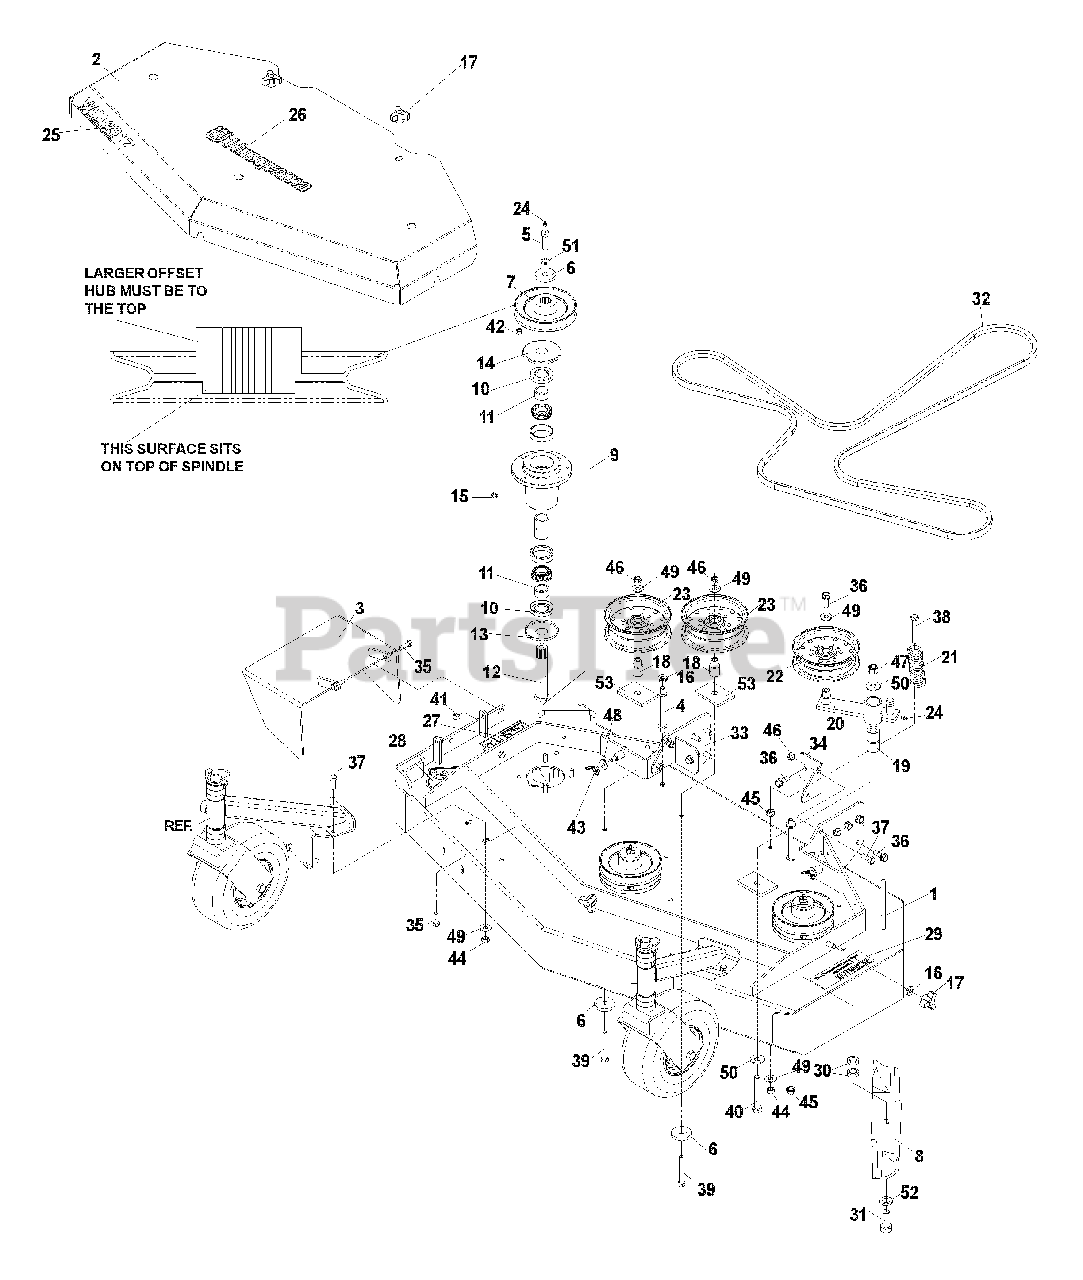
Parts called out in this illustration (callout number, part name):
1	48" DECK W/DECALS
2	SHIELD, BELT, 48"
3	DEFLECTOR CHUTE
4	SPACER, SHIELD
5	HCS, 7/16-20 X 1 1/2, GR5
6	HEAVY WASHER
7	PULLEY
8	BLADE, 16 1/4"
9	SPINDLE ASSEMBLY, COMPLETE
10	SHAFT SEAL
11	TOP & BOTTOM SPACERS
12	SPINDLE
13	DUST CUP, BOTTOM
14	DUST CUP, TOP
15	GREASE POPET
16	WASHER, 3/8, SEALING
17	KNOB, 3-PRONG
18	BUSHING, IDLER
19	BUSHING, PIVOT
22	IDLER PULLEY
23	IDLER PULLEY (TALL)
24	ZERK
25	DECAL, WHT 4817
26	DECAL, HUSQVARNA
27	DECAL, EURO SEVERING
28	DECAL, CPSC
29	DECAL, NASCAR
30	SPACER, BLADE
31	HCS, 5/8-18 X 1 1/2, GR5
32	BELT, DECK
33	DECK SLIDE, RIGHT
34	DECK SLIDE, LEFT
35	HCS, 5/16-18 X 1, GR5
36	HCS, 3/8-16 X 1, GR5
37	HCS, 3/8-16 X 1, GR5
38	HCS, 3/8-16 X 2 1/2, GR5
39	HCS, 3/8-16 X 2 3/4, GR5
40	HCS, 1/2-13 X 3 1/4, GR5
41	NUT, 5/16C, NYLOC
42	NUT, 5/16C, CENTER LOCK
43	NUT, 5/16C, WINGNUT
44	NUT, 3/8C, NYLOC
46	NUT, 3/8C, CENTER LOCK
47	NUT, 1/2C, NYLOC
48	WASHER, 5/16
49	WASHER, 3/8
50	WASHER, 1/2
51	LOCKWASHER, 7/16
52	LOCKWASHER, 5/8
